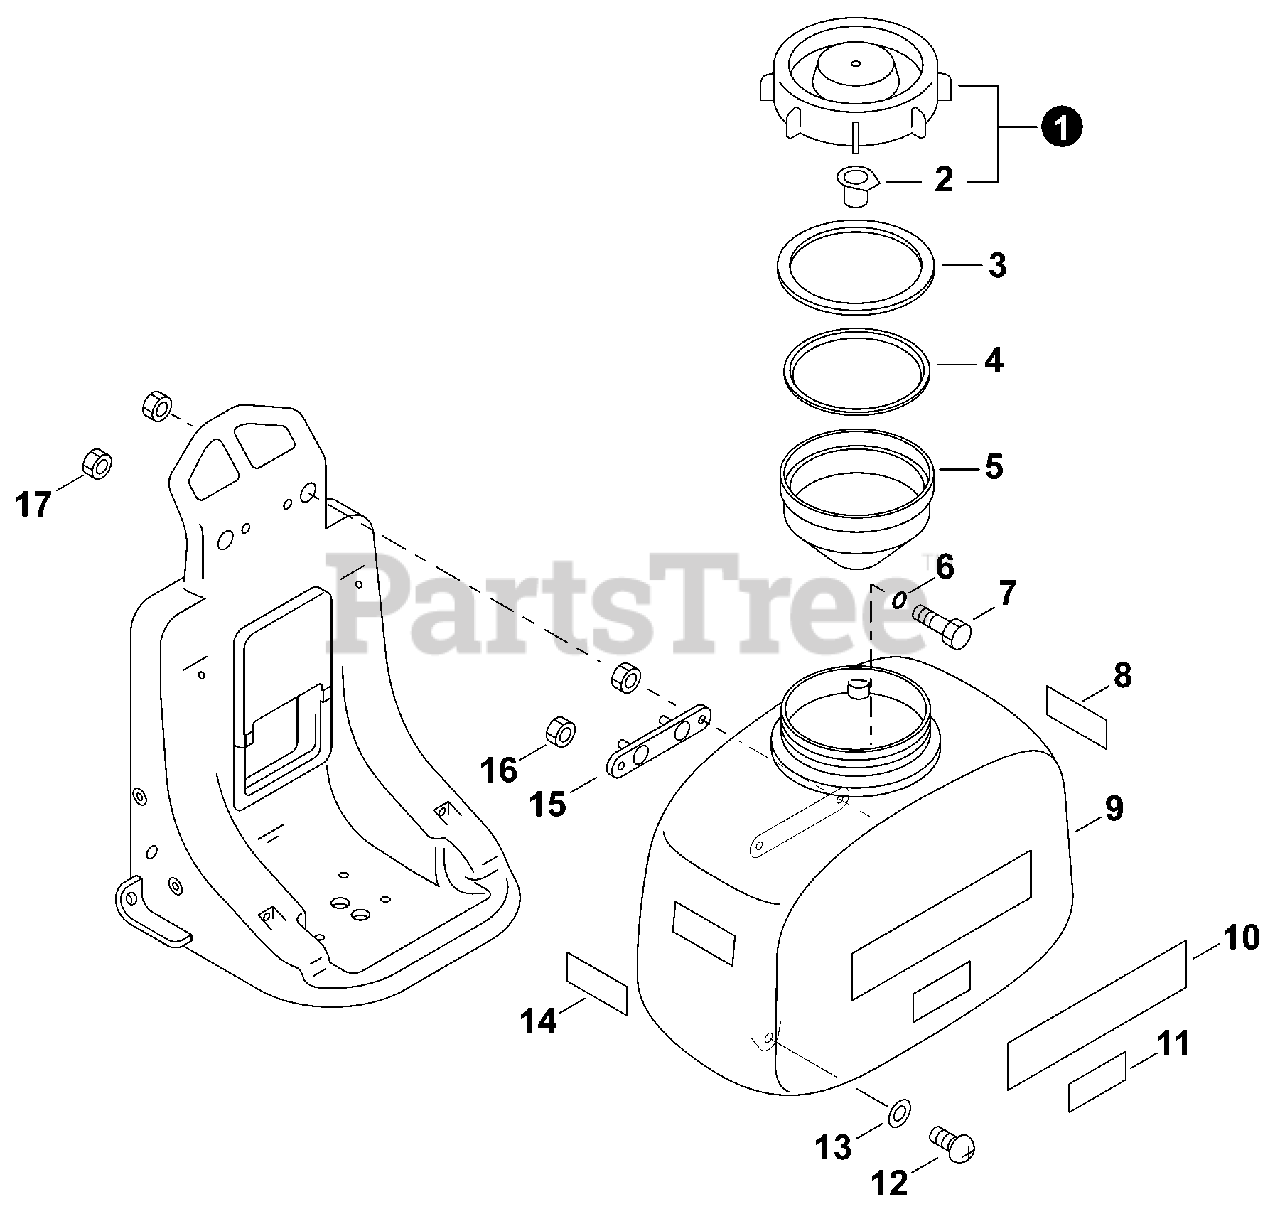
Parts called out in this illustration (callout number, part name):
1	CAP, CHEMICAL TANK
2	BREATHER
3	GASKET, CHEMICAL TANK
5	FILTER, TANK
6	O-RING P-10A
8	LABEL - CAUTION
9	TANK, CHEMICAL
10	LABEL - ECHO
11	LABEL - MODEL
12	SCREW, TAPPING
14	LABEL - CAUTION
15	BRACKET, TANK
16	NUT, FLANGE M6
17	NUT, FLANGE M6
